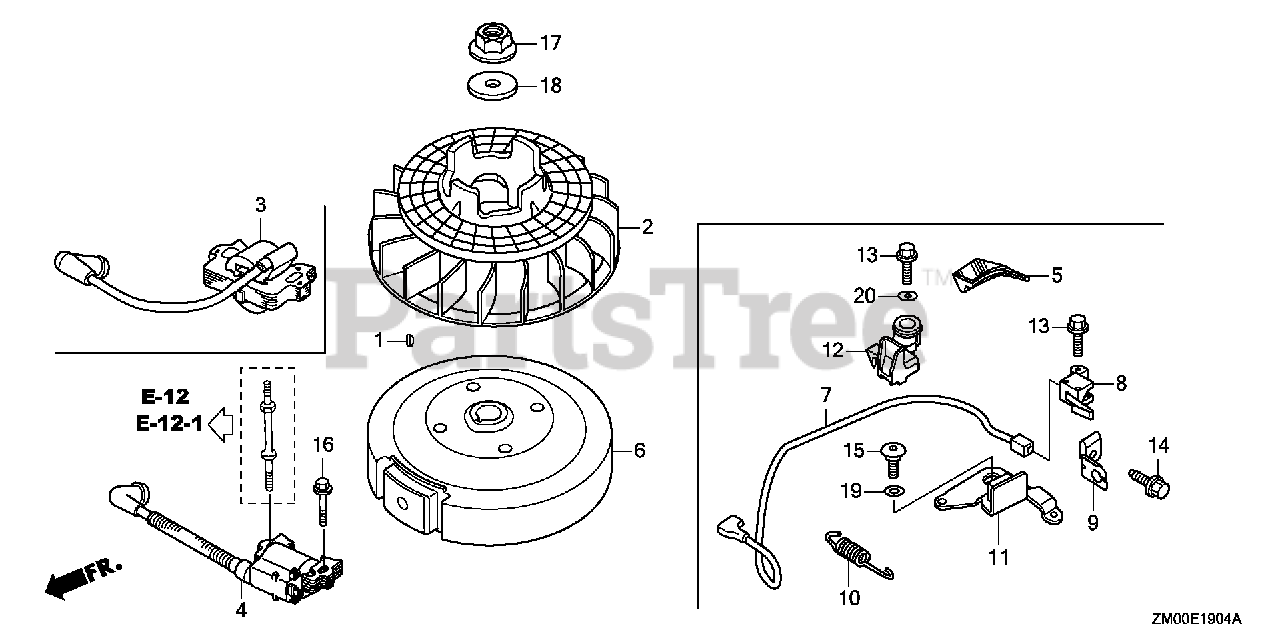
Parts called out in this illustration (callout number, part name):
1	KEY, SPECIAL WOODRUFF (25X18)
2	FAN, COOLING
4	COIL ASSY., IGNITION (PHELON)
6	FLYWHEEL (KOKUSAN)
16	BOLT, FLANGE (6X23)
17	NUT, SPECIAL (14MM)
18	WASHER (14X45)
